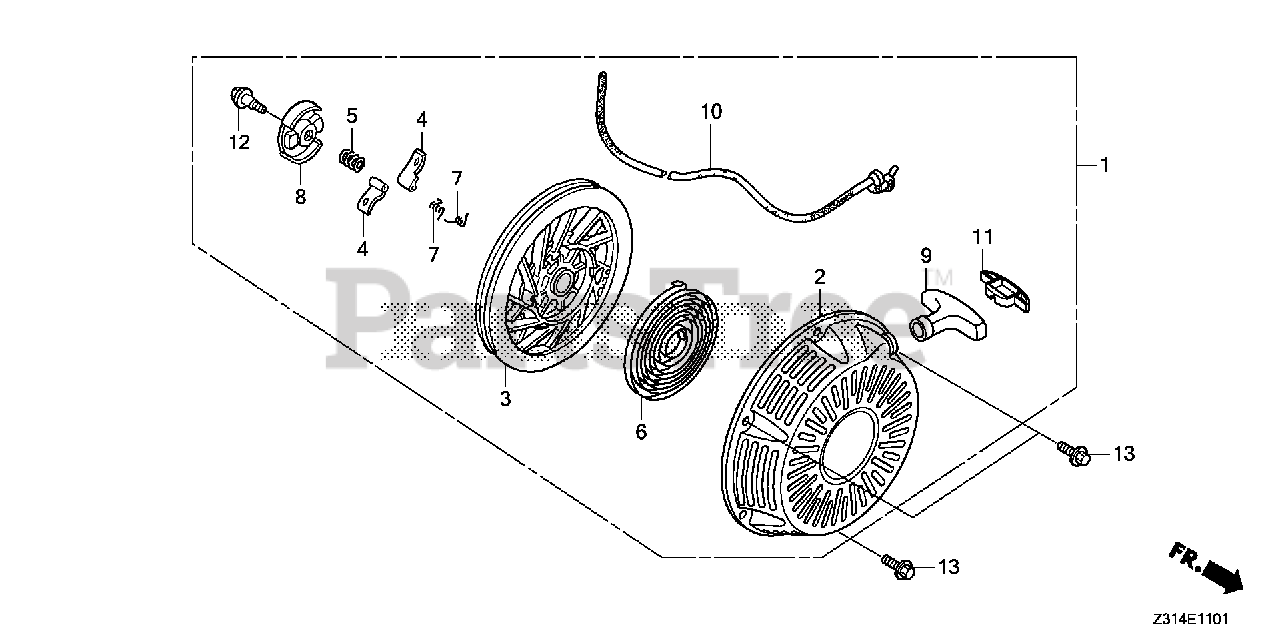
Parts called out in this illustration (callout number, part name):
1	STARTER ASSY., RECOIL *NH1* (COO) (BLACK)
2	CASE, RECOIL STARTER *NH1* (BLACK)
3	PULLEY, RECOIL STARTER
4	RATCHET, STARTER
5	SPRING, FRICTION
6	SPRING, STARTER RETURN
7	SPRING, RATCHET
8	RETAINER, SPRING
9	GRIP, STARTER
10	ROPE, RECOIL STARTER
11	GRIP, REINFORCEMENT
12	SCREW, CENTER
13	BOLT, FLANGE (6X10)
